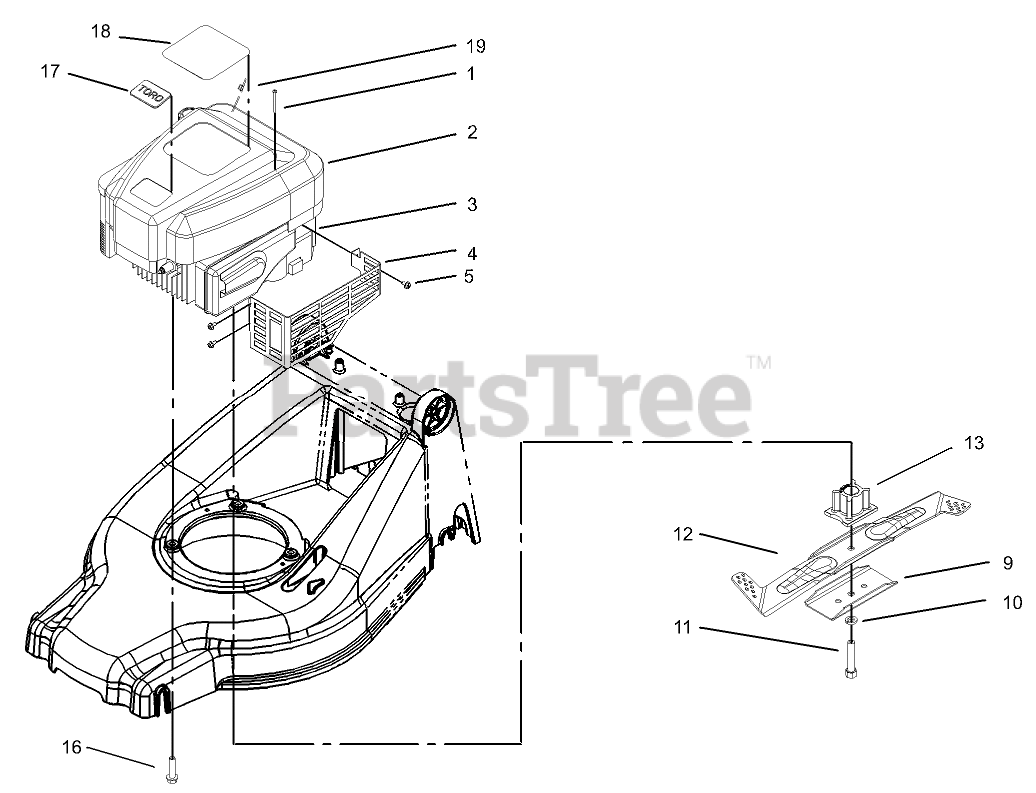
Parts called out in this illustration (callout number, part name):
1	SCREW-PPH
2	SHROUD-ENGINE
4	SHIELD-MUFFLER
5	SCREW-HWH
9	STIFFENER-BLADE
10	WASHER-LOCK
11	BOLT-BLADE
13	RETAINER-BLADE
16	SCREW-HWH
17	PLATE-LOGO
18	DECAL-ENGINE
19	STOP-ROPE
